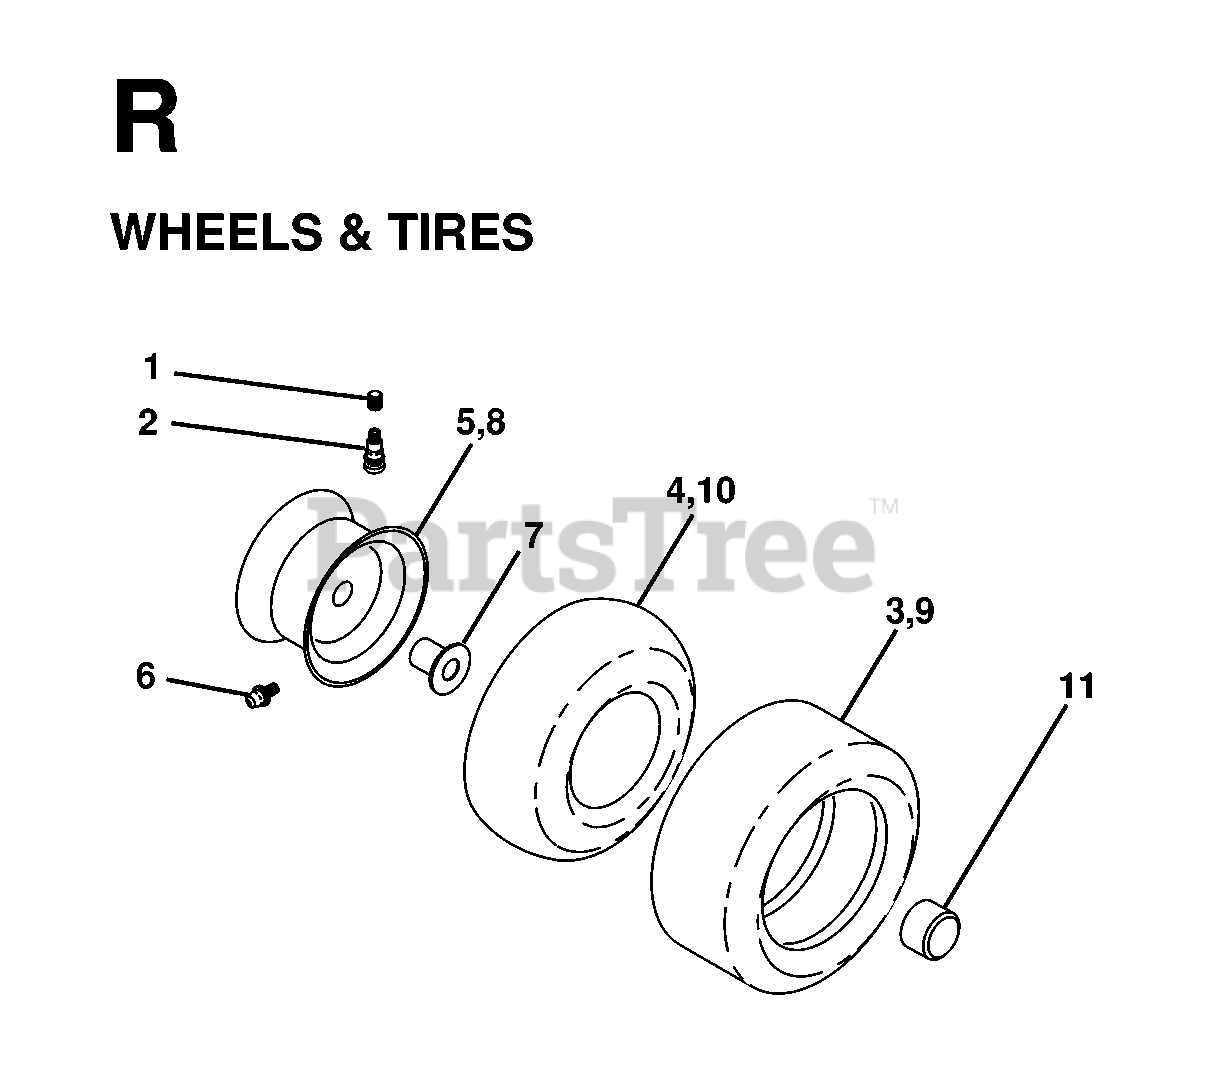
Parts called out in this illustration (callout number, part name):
1	VALVE CAP
2	VALVE STEM LT
3	TIRE HEAVY DUTY
4	TUBE.5.3/4.5/6
5	RIM ASM 6" FRONT SILVER
6	FITTING LT
7	BEARING T
8	RIM ASM 8" REAR SILVER
9	TIRE HEAVY DUTY
10	TUBE
11	CAP-HUB FRONT LT
